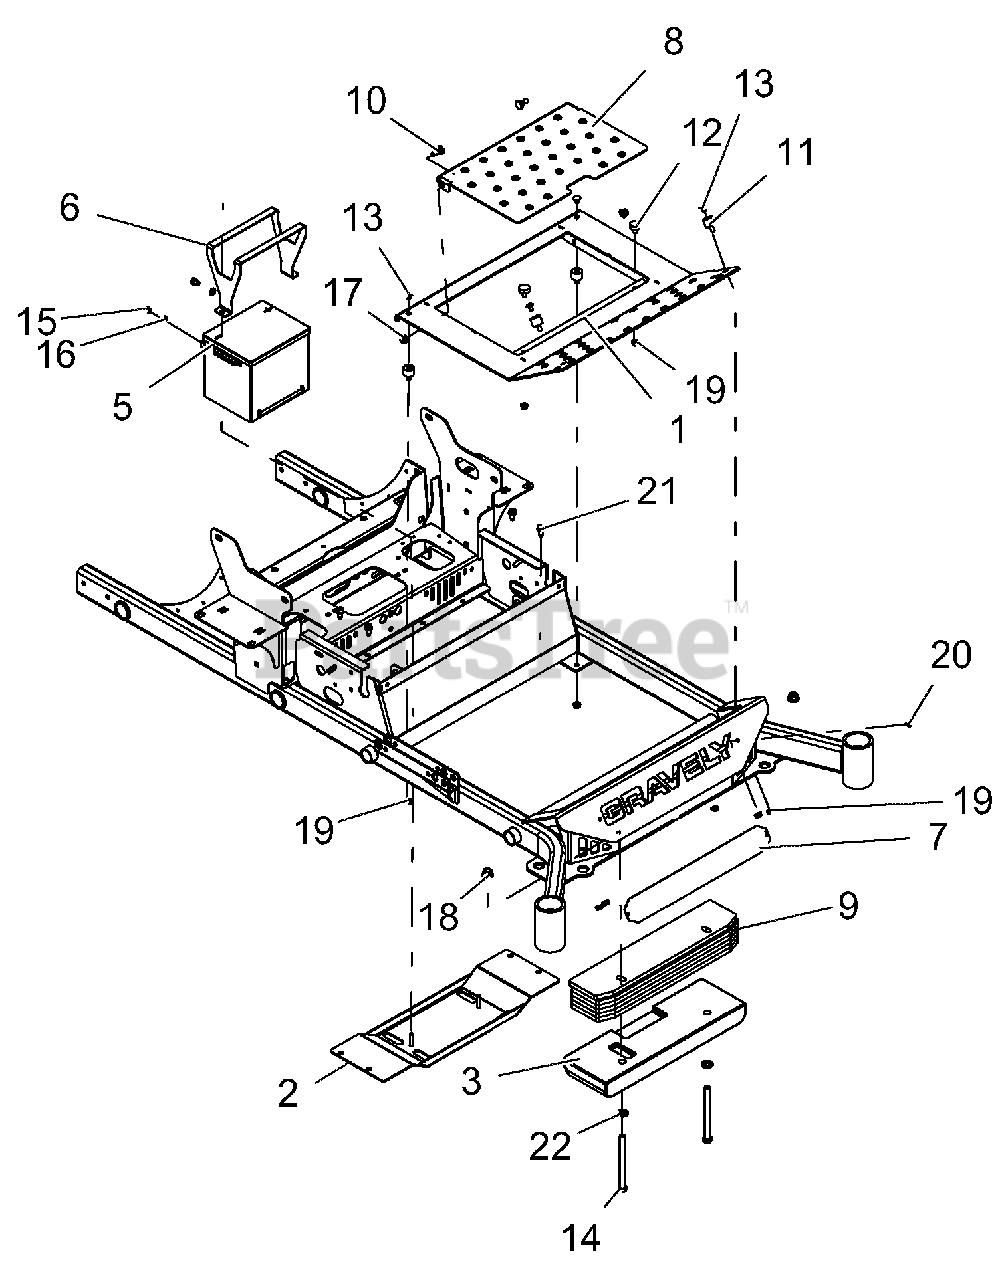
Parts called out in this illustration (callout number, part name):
1	WLDMT, FOOT PLATE-RED
2	WLDMT, PT400 DIESEL BATTERY TRAY
3	WEIGHT, CAST IRON
5	BATTERY, GROUP 70, 540 CCA
6	BRKT, BATTERY HOLD-DOWN
7	PLATE, BUMPER LOGO BACKING-BLACK
8	PANEL, INSPECTION
9	WEIGHT, COUNTER
10	BLT, SHLDR EP .38-16X.30 HEX YZ
11	BUMPER, STUD MOUNTED W/FEMALE INSERT
12	BUMPER, RUBBER
13	@BLT-RDHDSQNK .31-18X.50 G5 YWZC
14	BLT-HEX .50-13X6.00 GR5 YWZC
15	BLT-HEX .38-16X.50 GR5 YWZC
16	@WSHR-LK .38X.094 REG YWZC
17	NUT-LK-NYL-FLG .38-16 YWZC
18	NUT-LK-NYL-FLG .50-13 YWZC
19	@NUT-SPNLK-FLG .312-18 YWZC
20	SCR-TAP .25-20X.50 HWH TR YWZ
21	SCR-TAP .38-16X.75 HWH TR YWZ
22	@WSHR-FL-STL.531X1.06X.095YWZC
